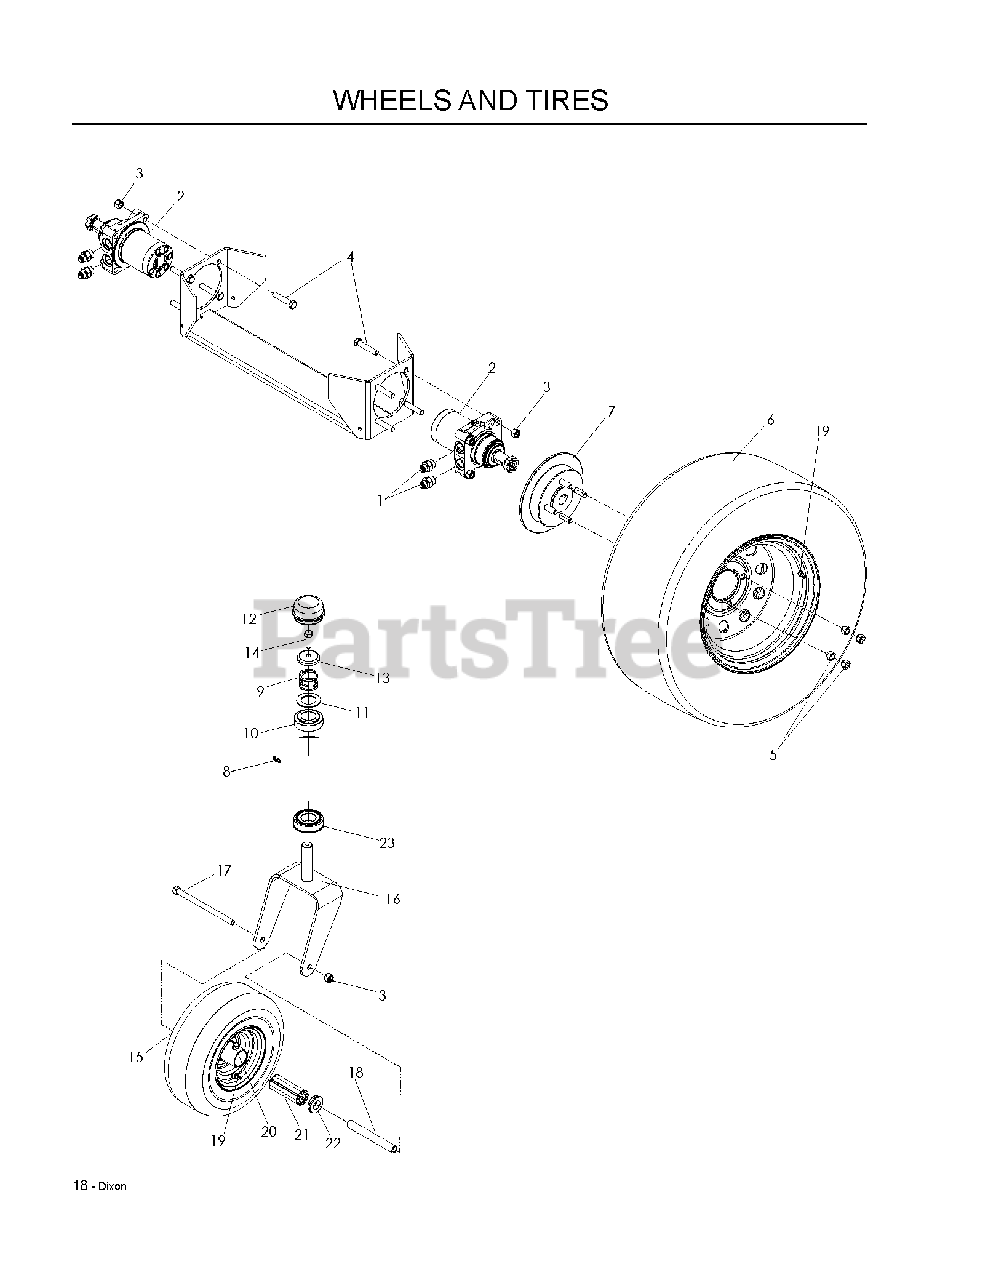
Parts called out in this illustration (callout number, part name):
1	CONNECTOR, STRAIGHT
2	WHEEL MOTOR, TJ
3	NUT 1/2-13 HEX NYLOC ZD
4	HEX SCREW 1/2-13 X 2.5" GR 5
5	LUG NUT 1/2F
6	RP.WHEEL.ASM.23X10.5-12.TURFMA
6	RIM 2.5" NEG OFFSET 8.5" WIDE
6	TIRE.TURF.MASTER.23X10.5-12
8	ZERK, 3/16, DRIVE IN
9	SPRING, CASTER
10	BUSHING, CASTER
11	WASHER, 1.025 ID X 1.64
12	GREASE CAP
13	CASTER.PLUG
14	HCS 5/16C X 1
15	TIRE.ASSEM.13X5-6.SMOOTH.SILVE
16	YOKE, CASTER - BLUE
17	SCREW 1/2C X 7 1/2 HEX CAP
18	SPACER, CASTER
19	VALVE STEM TR-412
20	ZERK 1/8 NPT
21	ROLLER BEARING
22	BEARING RETAINER
23	BEARING FLANGED
